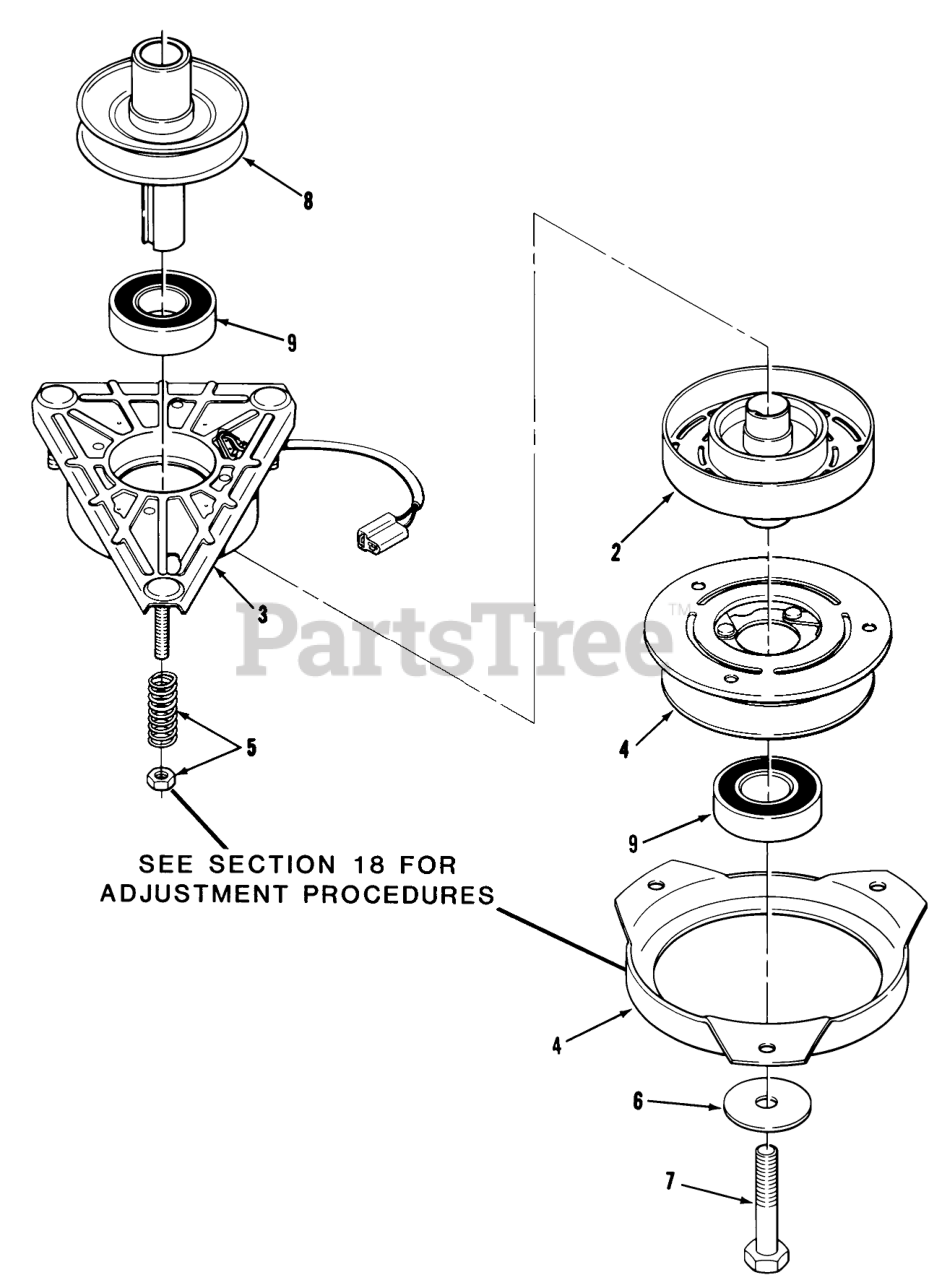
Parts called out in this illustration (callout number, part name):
4	ASS'Y-ARMATURE
5	ACCESS SPRING & NUT
6	WASHER
9	BEARING-ELEC CLUTCH
